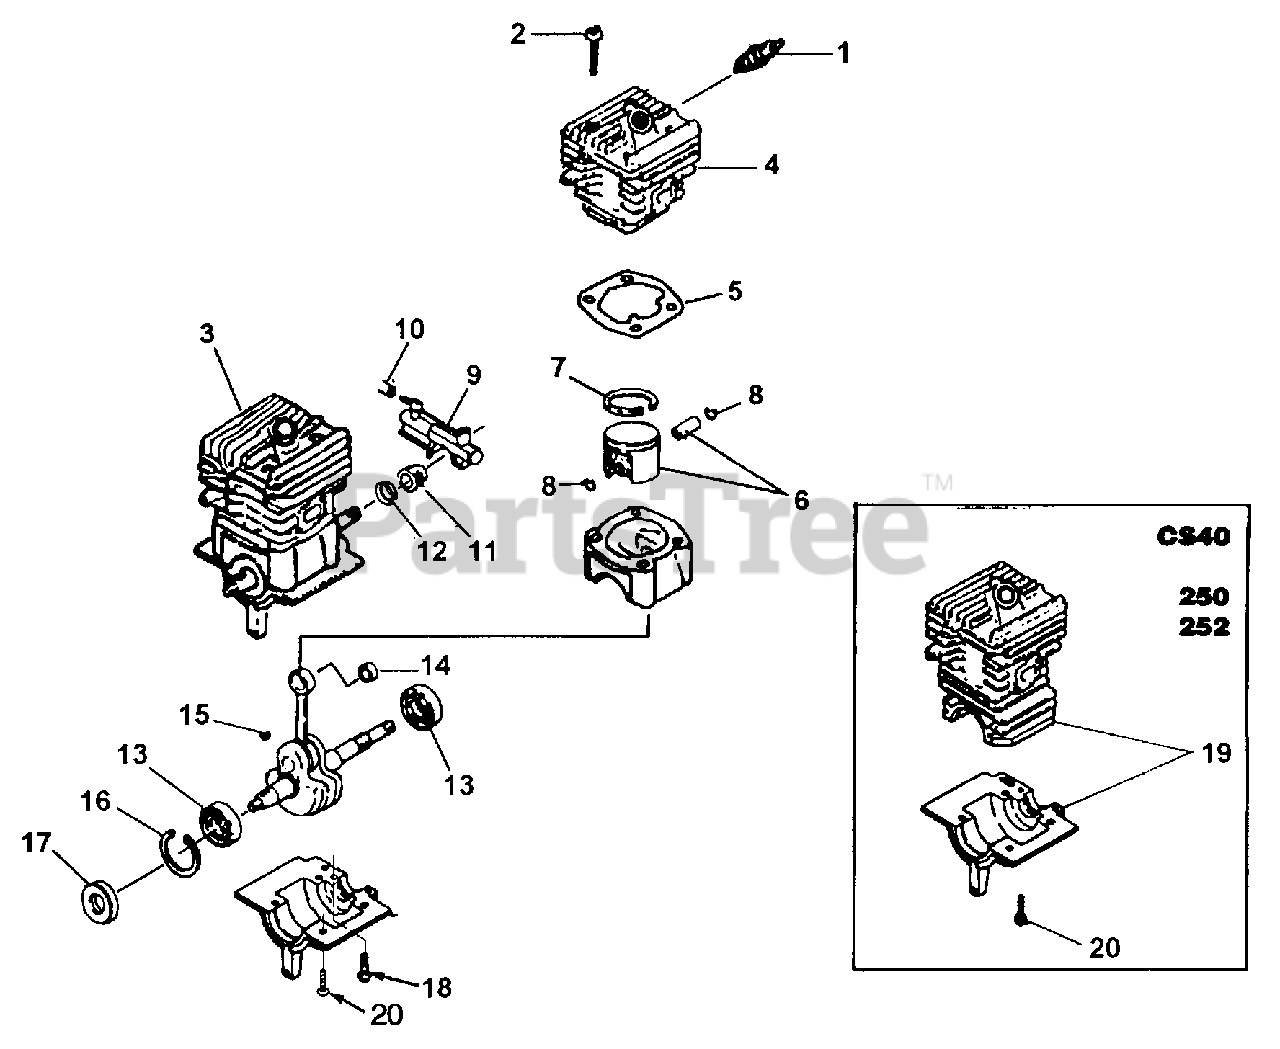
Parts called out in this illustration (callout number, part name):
1	SPARK PLUG (CJ6Y)
2	SCREW-PAN Hd. (10-24 x .800)
3	SHORT BLOCK
4	CYLINDER & GASKET
5	GASKET, CYLINDER
6	PISTON & PIN
7	RING, PISTON
8	RING, WRIST PIN RETAIN.
9	OIL PUMP
10	TUBING, OIL (TO GUIDE BAR)
11	WORM GEAR, LEFT HAND
12	SEAL, CRANKSHAFT
13	BEARING, BALL
14	BEARING, NEEDLE
15	WOODRUFF KEY
16	RETAINING RING
17	SEAL, SHAFT
18	SCREW,OIL PUMP (8-32 X 5/8")
19	CYLINDER & CRANKCASE
20	SCREW, Hex Hd. (12-24 X 7/8")
